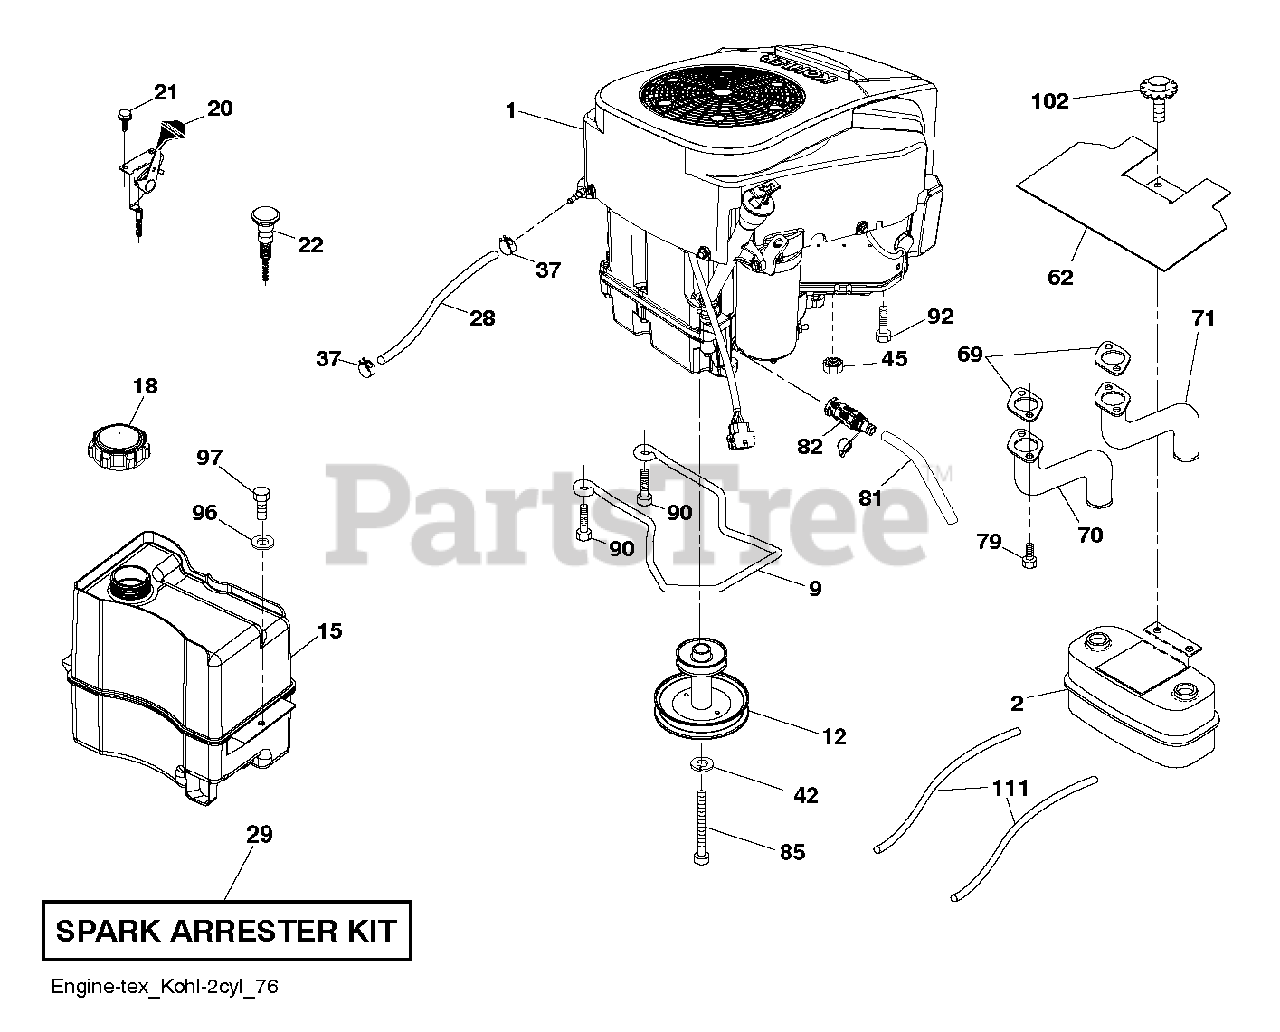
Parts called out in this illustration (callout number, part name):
2	MUFFLER.ASM.TWN.EXTNDED.DFLCTR
9	KEEPER.BELT.ENG.4.25"2.BLT.431
12	ENGINE.PULLEY
15	Front Tank Assembly, 2.5 Gallon
18	CAP.2.25'.VENTED.TETHER .EPA
20	THROTTLE CONTROL
21	SCREW.#10 X 0.750.BOS
22	CONTROL.CHOKE.ERGO.PUSH-IN.BLA
28	Fuel Hose, 1/4" Low Perm
29	KIT.SPARK ARRESTOR 794945 B&S
37	HOSE CLAMP
42	WASHER 7/16 LOCK
45	NUT
62	SHIELD.HEAT.MUFFLER
69	GASKET.EXHAUST.KOHL.CV18-CV26
70	PIPE.EXHAUST.LH.CV18/20
71	PIPE.EXHAUST.RH.CV18/20
79	SCREW.SOCKET HD.5/16-1
81	TUBE, DRAIN OIL ASM.
82	VALUE.OIL.DRAIN
85	BOLT.HEX.7/16-20X4.GR5.1.5BLUE
90	SCREW 3/8-16X1
92	SCREW 3/8-16X1
97	SCREW HEXWSHR 1/4-20X3/4
102	SCREW
111	RP PURGE LINE
